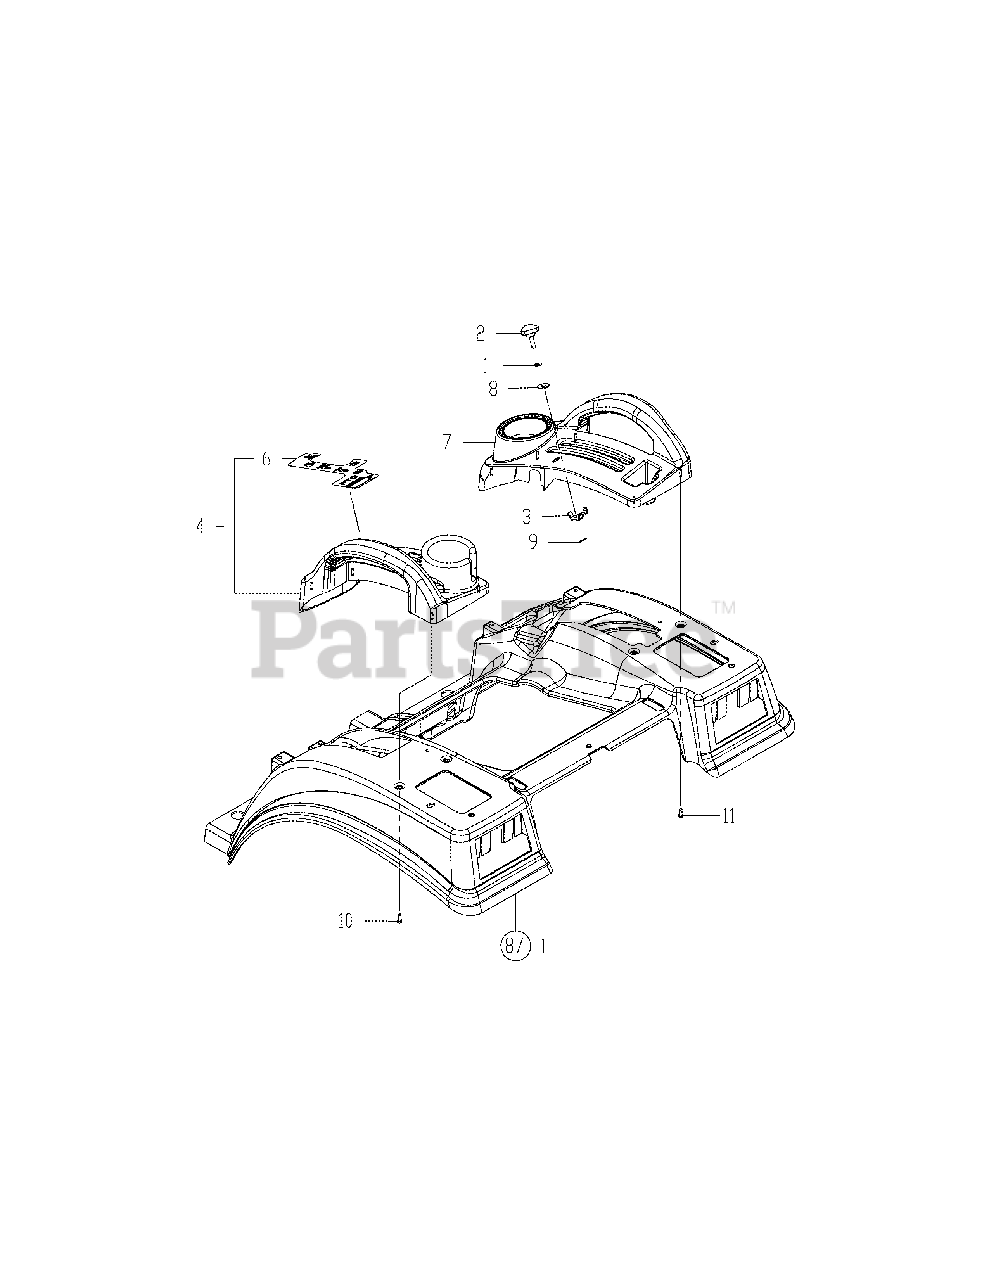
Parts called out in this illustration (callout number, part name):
2	Knob, Hyd. Control
3	Stopper, Hyd. Control
4	Guide M Asy, Lever L
6	Label, Leverguide L
7	Guide, Lever R
10	Screw, 6.0 X 16
11	Screw, 6.0 X 16
